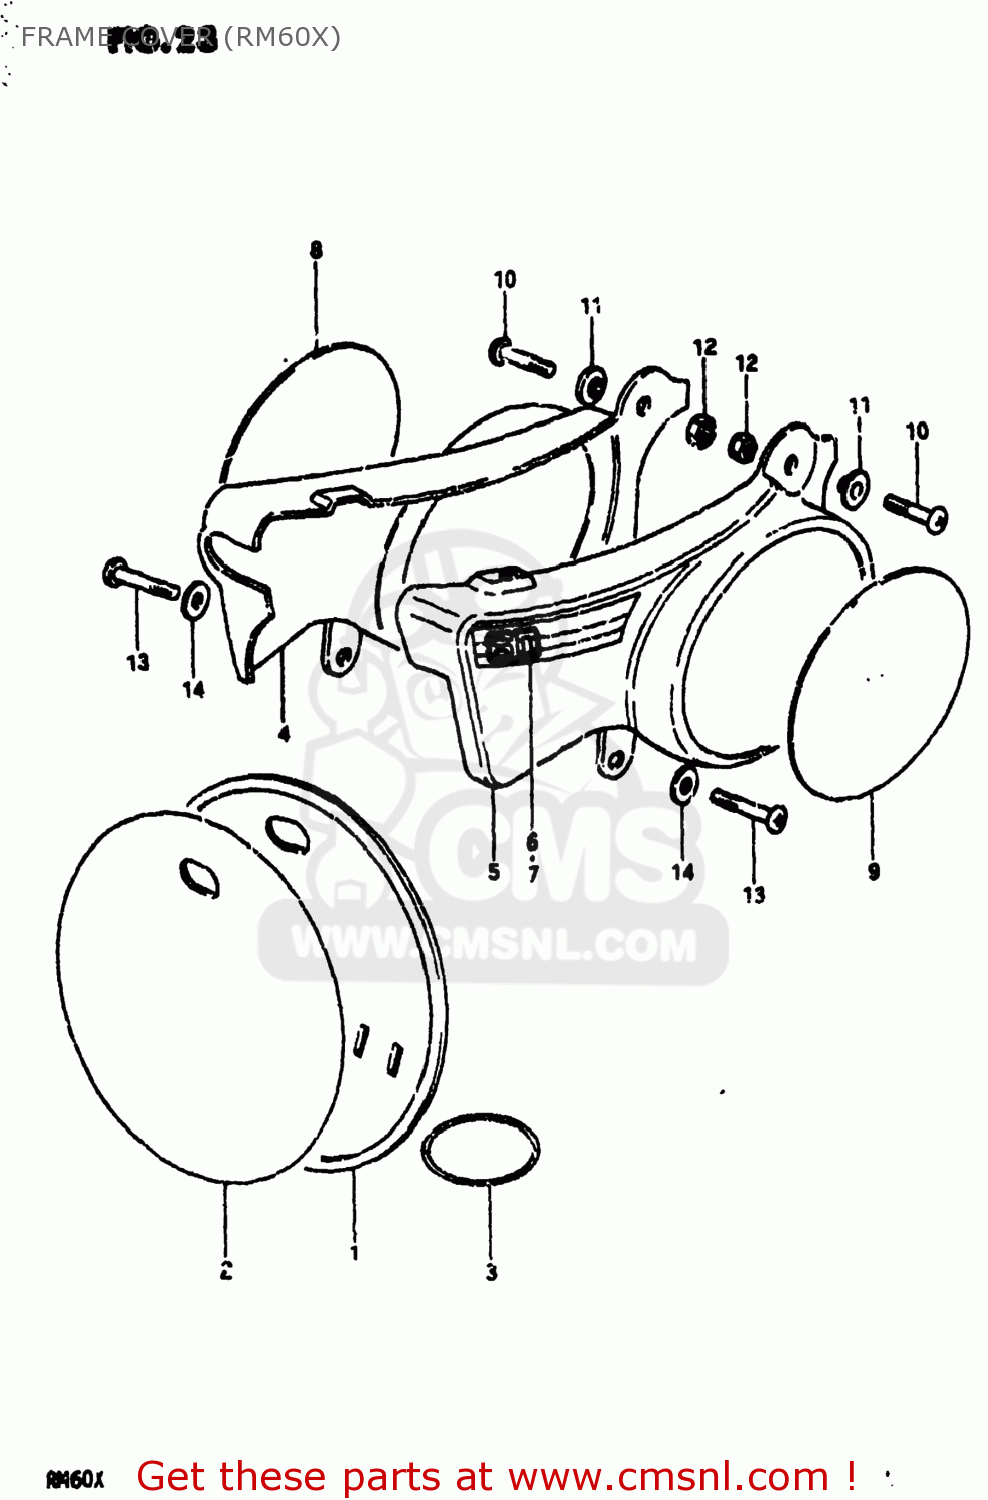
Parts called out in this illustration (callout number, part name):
1	PLATE,NUMBER,FRONT
2	EMBLEM,FRONT NUMBER PLATE
3	O-RING
4	COVER,FRAME,RIGHT
5	COVER,FRAME,LEFT
6	TAPE,FRAME COVER
7	TAPE,FRAME COVER
8	TAPE,FRAME COVER NUMBER PLATE
9	LABEL,FRAME COVER
10	SCREW
11	WASHER
12	NUT
13	SCREW
14	WASHER
